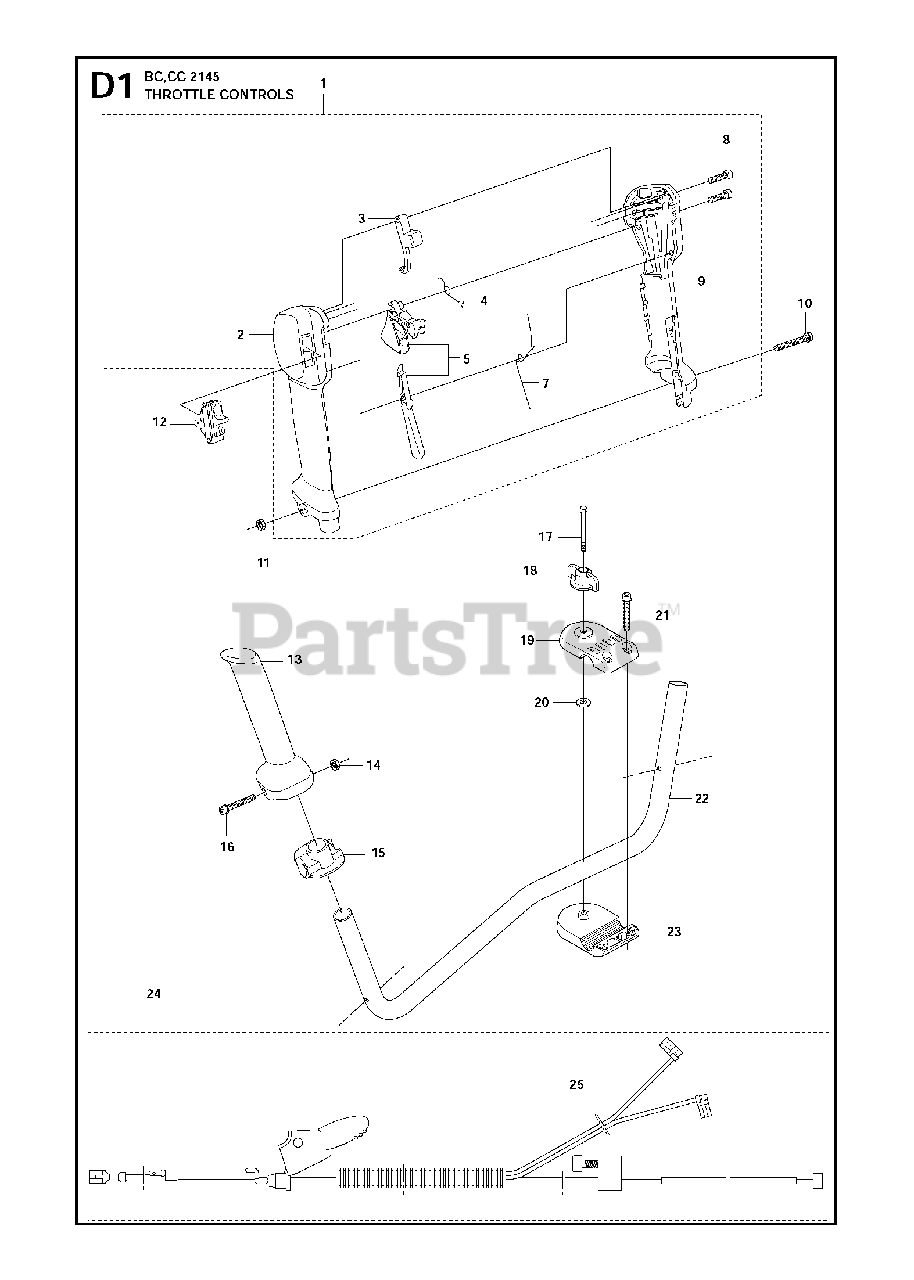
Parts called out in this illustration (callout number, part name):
1	THROTTLE HANDLE ASSY
3	SWITCH
4	SPRING
5	THROTTLE CONTROL
7	SPRING
8	SCREW
9	HANDLE HALF RIGHT
10	%SCREW
12	STOP BUTTON
14	NUT M6M M5
15	HANDLE FASTENER
17	SCREW 6X70
19	HANDLE BRACKET
23	HANDLE BRACKET
24	WIRING ASSY
25	SCREW
